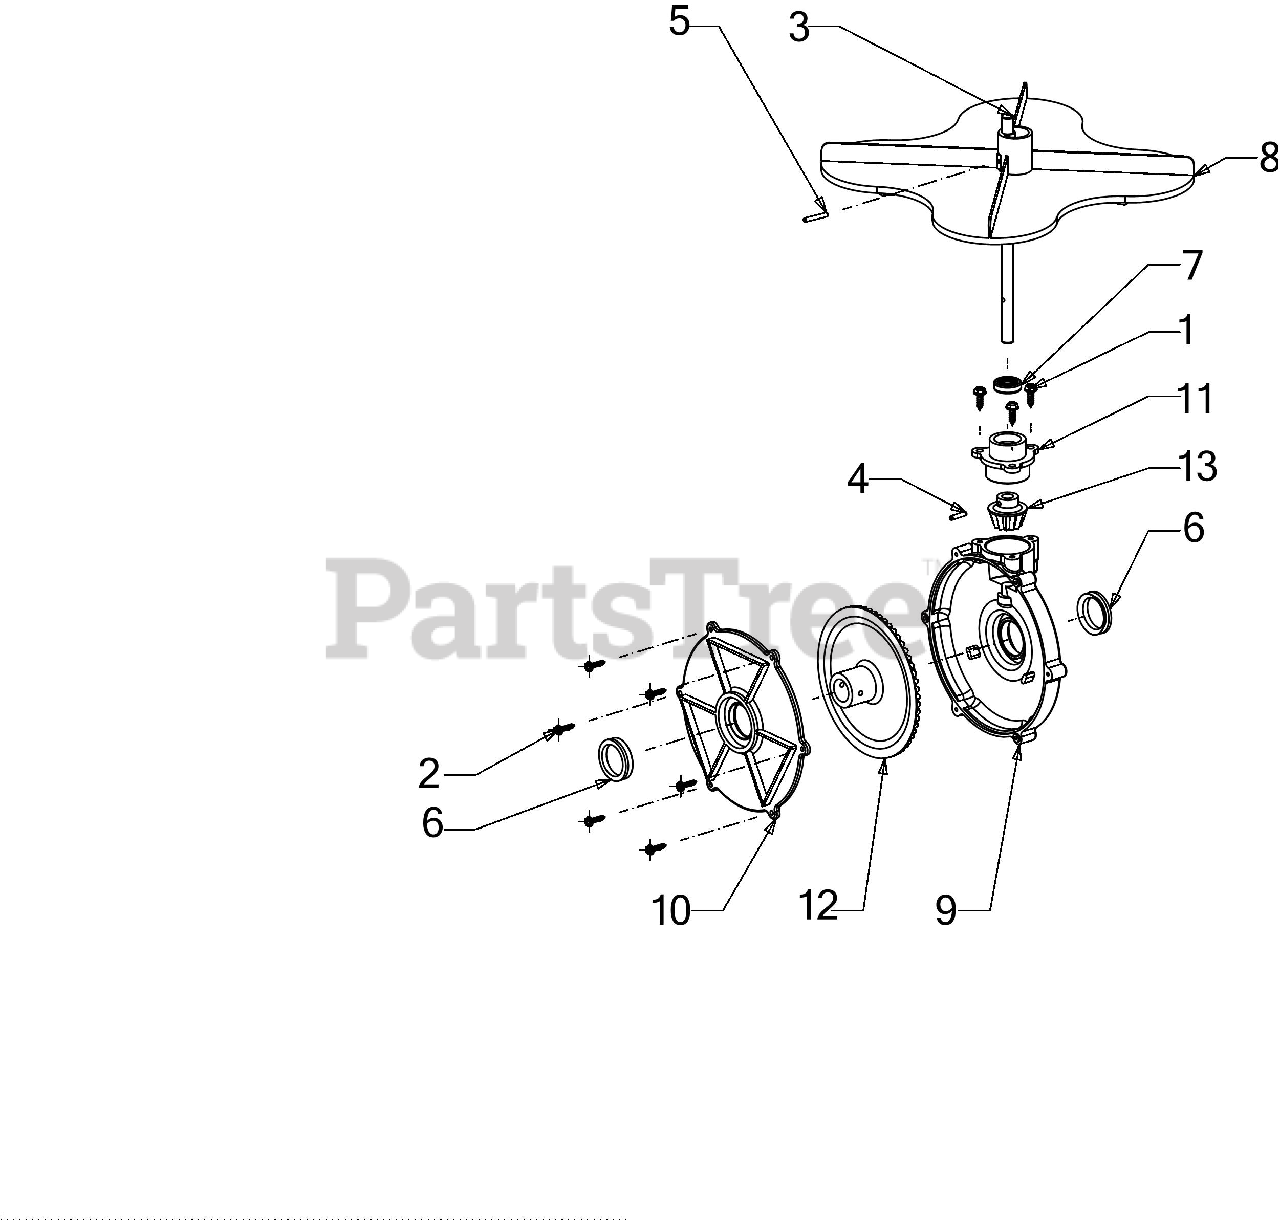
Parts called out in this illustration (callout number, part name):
1	SCREW: #10-16X.625
2	SCREW: #6-20X.625
3	IMPELLER SHAFT
4	ROLL PIN - 5/32X.625
5	ROLL PIN - 1/8 x .875
6	HOUSING SEAL
7	GEAR SET CAP SEAL
8	SPREADER IMPELLER
9	GEAR SET HOUSING
10	GEAR SET COVER
11	GEAR SET CAP
12	BEVEL GEAR
13	PINION GEAR
